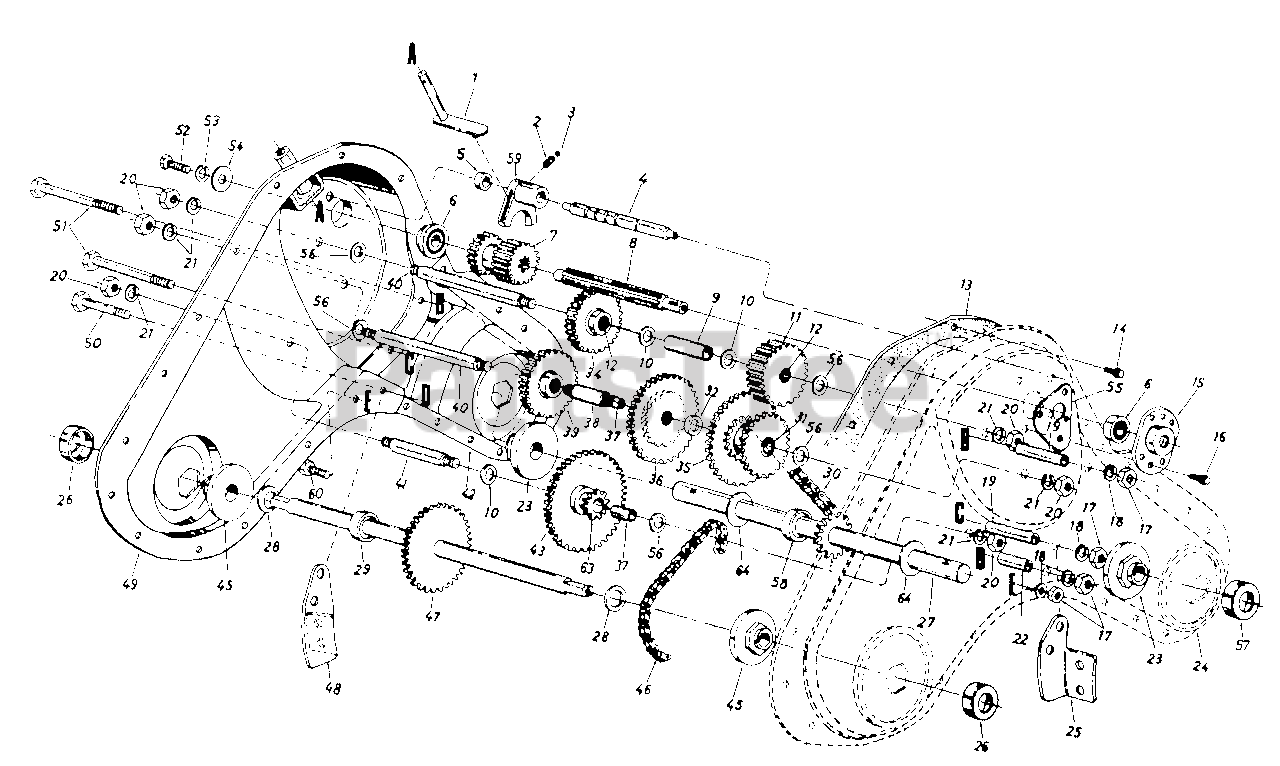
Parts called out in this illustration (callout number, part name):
1	BRACKET ASSY-SHIFT
2	SPRING-COMPRESSION
3	BALL-DETENT
4	SHAFT-DETENT
5	SPACER-.505 1D
6	BEARING-BALL
7	GEAR-SPUR-16T
8	SHAFT-INPUT
10	WASHER-FL-.640ID X 1.24OD X .06HDN
11	GEAR-SPUR-30T
12	BEARING-NEEDLE
13	GASKET
14	SCREW-HEX WASH SF TAPP
15	HOUSING-BRG
16	SCREW-HEX HD TAP 1/4-20 X 7.5
17	NUT-HEX 5/16-18
18	WASHER-LOCK-5/16
19	SPACER-1.560 1D
20	NUT-HEX 7/16-20
21	WASHER-FL
22	SPACER-1.015 1D
23	BEARING
24	HOUSING ASSY-LH
27	SHAFT ASSY-TINE
28	WASHER-FL
29	SPACER
30	#50 CHAIN 5/8 PITCH X 52L E
31	BEARING-NEEDLE
32	WASHER-FL
34	GEAR-SPUR-30T
35	GEAR-30/44T
36	GEAR-SPUR-44T
37	BEARING-SLEEVE .627 X .750 X .936
39	GEAR-SPUR-30T
40	JACKSHAFT
41	JACKSHAFT
46	#420 CHAIN-1/2 PITCH
47	SHAFT ASSY-WHEEL
51	SCREW-HEX
52	BOLT - 1/4-28 X 5/8 61.5
53	WASHER-LOCK-3/8
54	WASHER-FL
55	BRACKET-GEAR POS
56	WASHER-FL
57	COVER-DUST
58	SPACER
59	FORK-SHIFT
60	SCREW-HEX 5/16-18 X .75
63	SPROCKET ASSY-10T
64	WASHER-FL-1.03 ID X 1.62 X .03 HD
